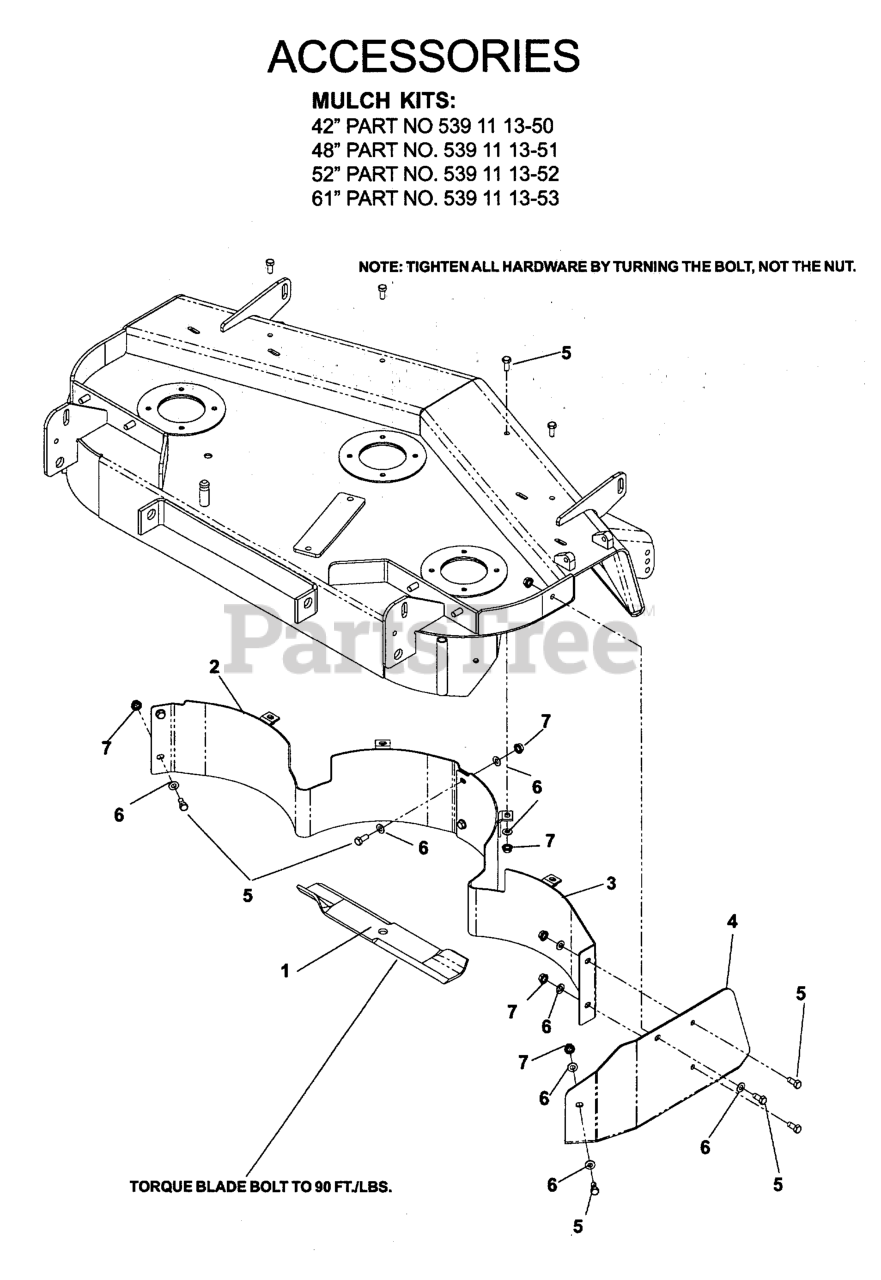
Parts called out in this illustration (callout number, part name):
1	BLADE MULCH 14-7/8"
2	MULCH BAFFLE, LEFT, 42
3	BAFFLE WLDMT, 42" R.H. MULCH
4	MULCH CAP 42"
5	HCS 5/16C X 3/4
6	FLAT WASHER 5/16 SAE
7	NUT 5/16C WHIZ
